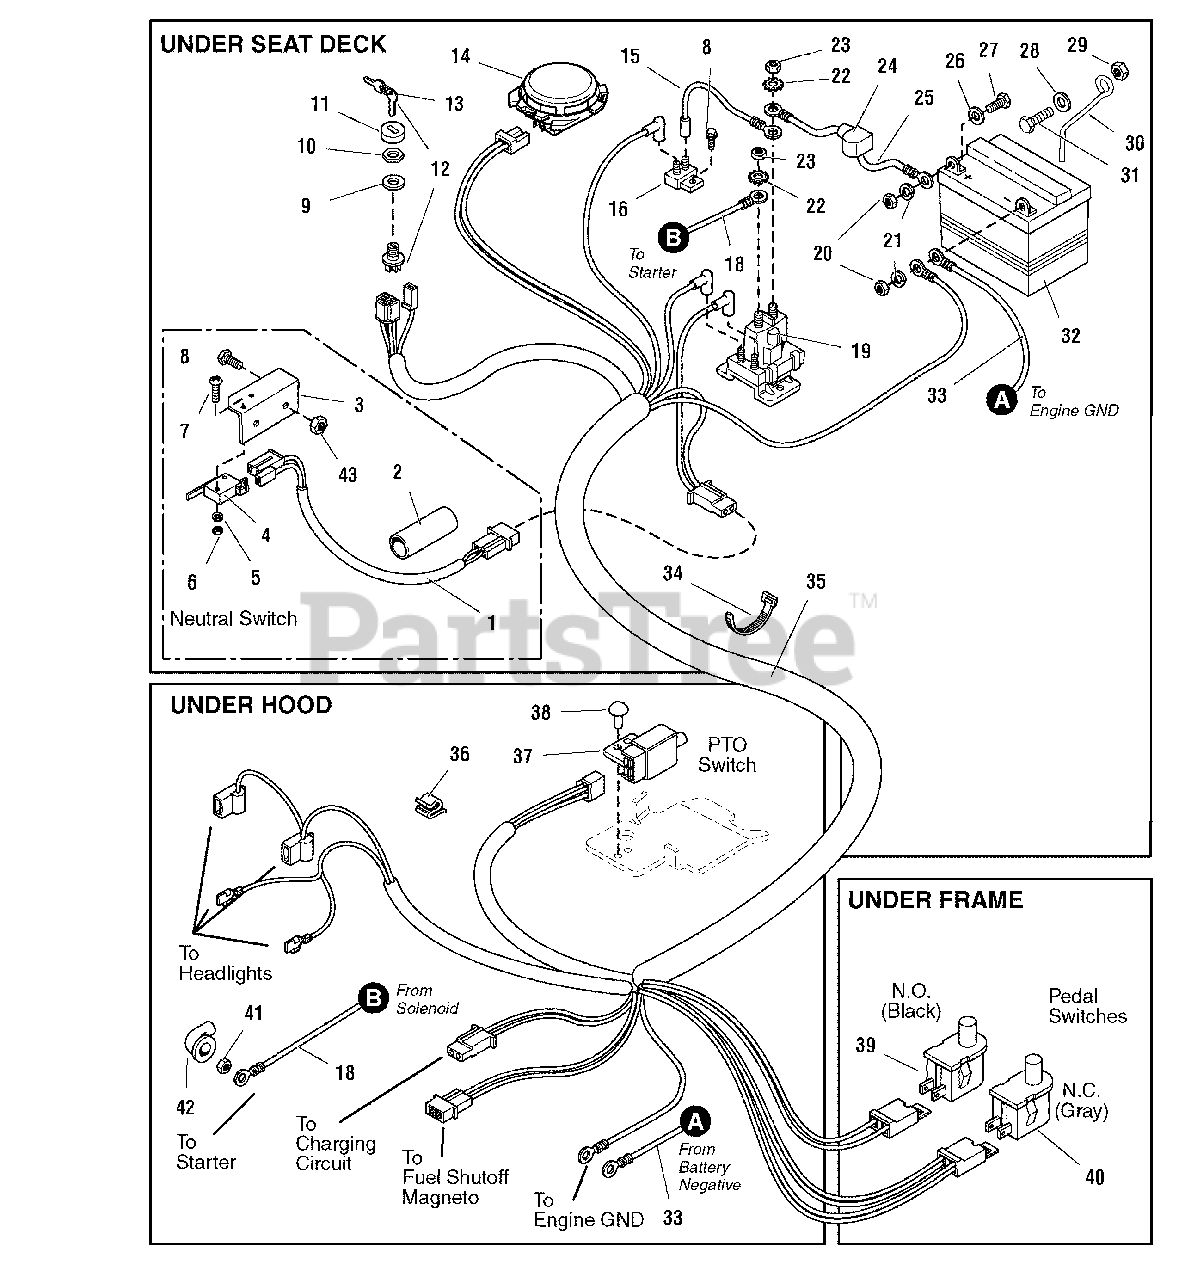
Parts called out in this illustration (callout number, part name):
1	WIRE ASSEMBLY
2	TUBE, Shrink
3	PLATE, Neutral Switch
4	SWITCH, Neutral Safety
5	LOCKWASHER, Spring, 1/8
6	NUT, Hex Machine, #4-40
7	CAPSCREW, Round Head, Phillips, #4 - 40 x 3/4
8	CAPSCREW, Hex Whizlock, 1/4-20 x 3/4
9	WASHER, 5/8
10	NUT, Hex, Flange, 5/8-32
11	COVER, Ignition
12	SWITCH, Ignition, 6-Pole (Includes Ref. 21, 23, 24, 25 & 26)
13	IGNITION KEY (Set of 2)
14	SWITCH, Seat
15	WIRE ASSEMBLY
16	CIRCUIT BREAKER
18	CABLE, # 6 x 42-1/2 long (Solenoid to Starter)
19	SOLENOID
20	NUT, Hex, 1/4-20
21	LOCKWASHER, 1/4
22	LOCKWASHER, External Tooth, 5/16
23	NUT, Hex, 5/16-24 NF
24	BOOT, Insulator
25	CABLE, # 6 x 10 Long, with 2 Ring Terminals
26	WASHER, Plain, 1/4
27	CAPSCREW, Hex Head, 1/4-20 x 3/4
28	WASHER, Plain, 5/16
29	NUT, Hex Nylon Lock, 5/16-18
30	ROD, Battery Hold Down
31	CAPSCREW, Hex Head, 5/16-18 x 3/4
33	CABLE, # 6 x 52-1/2 long (Battery to Ground)
34	TIE-SELF LOCKING
35	HARNESS, Wiring
36	CLIP, Wire
37	SWITCH, Neutral Start
39	SWITCH, Pedal, N.O., Black
40	SWITCH, Pedal, N.C., Gray
41	NUT, Hex Flange, Whiz Lock, 1/4-20
42	COVER, Terminal
43	NUT, Hex Flange, 1/4-20
